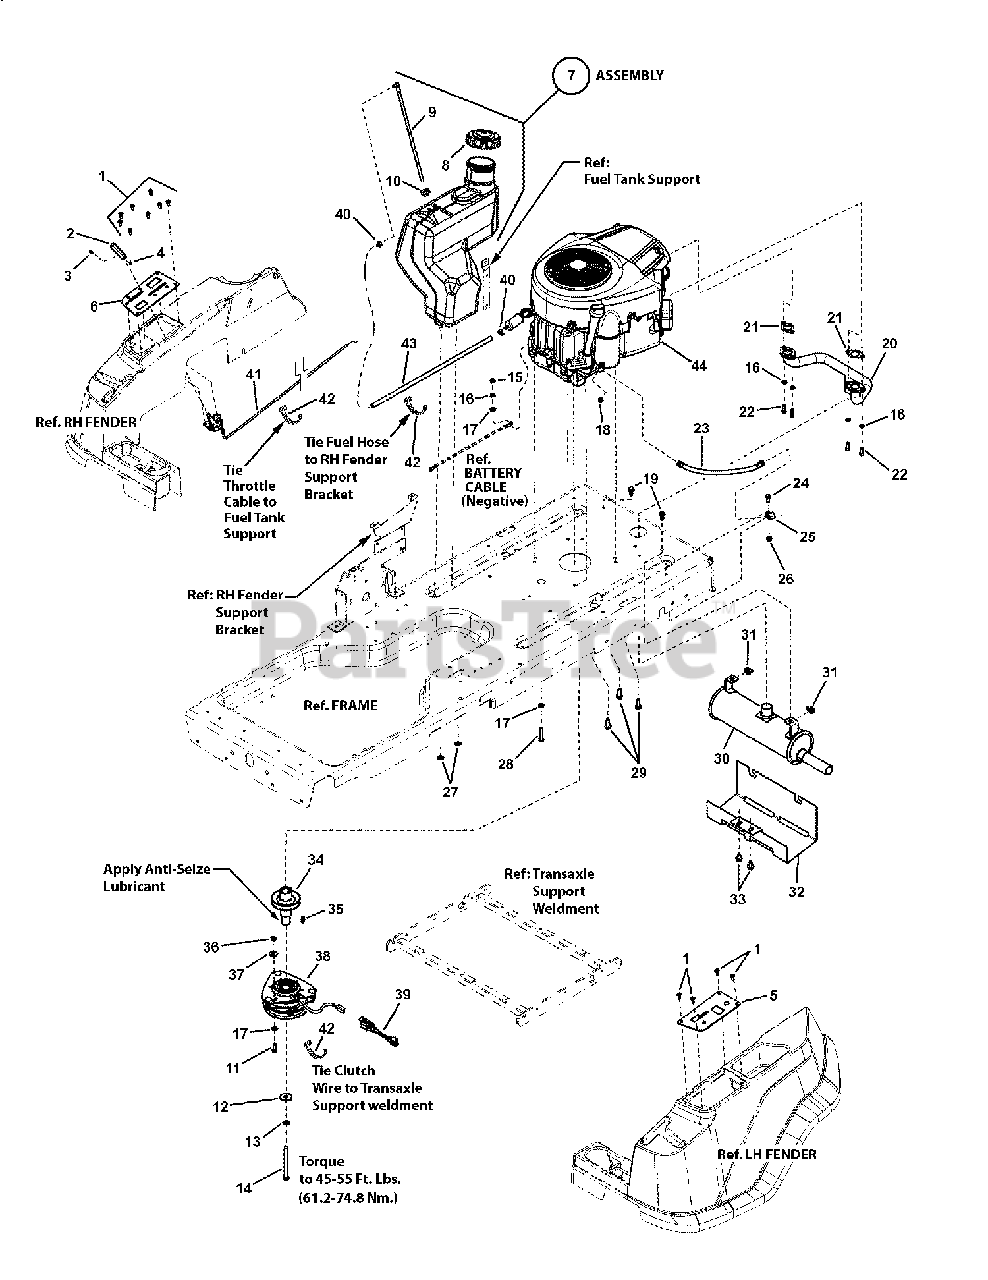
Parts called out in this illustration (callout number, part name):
1	SCREW, 1/4-20 x 5/8" Pan Head Self-Tap (Torx)
2	KNOB, Throttle, Red
3	SCREW, #8-32 x 3/8" Cross Recess Filister Head, GR 2
4	NUT, #8-32 Hex, GR 2B
5	PANEL, Control, LH
6	PANEL, Control, RH
7	ASSEMBLY, Fuel Tank, 3 Gallon (incl. 4 items shown below)
8	CAP, Fuel Tank
9	ASSEMBLY, Elbow, Pickup Tube
10	BUSHING, Fuel
11	SCREW, 5/16-18 x 7/8" Hex Head Cap, GR 5, YZ
12	WASHER, .468 ID x 1-1/2" OD x .188 Flat, YZ
13	WASHER, 7/16" Split Lock, YZ
14	SCREW, 7/16-20 x 4-1/2" Hex Head Cap, GR 5
15	NUT, 5/16-18 Hex, GR 5 or B, YZ
16	WASHER, 5/16" Split Lock
17	WASHER, 5/16" Flat
18	NUT, 1/4-20 Hex Flange Lock, GR 5, YZ
19	SCREW, 5/16-18 x 3/4" Hex Flange Lock, Black
20	MANIFOLD, B&S V-Twin
21	GASKET, Exhaust B&S Reg (No Chre) 273485
22	SCREW, 5/16-18 x 3/4" Allen Socket Head, GR 8 Black
23	HOSE, Oil Drain
24	SCREW, 5/16-18 x 3/4" Hex Head Cap, GR 5, YZ
25	HARNESS CLIP, 5/8"
26	NUT, 5/16-18 Flange Lock, YZ
27	RETAINER, 3/8" Bolt
28	SCREW, 5/16-18 x 1-3/4" Hex Head Cap, GR 5 YZ
29	SCREW, 3/8-16 x 1" Hex Washer Self-Tap
30	MUFFLER, RZT
31	NUT, Speed, Lug Type, 5/16-18
32	HEAT SHIELD, Muffler
33	SCREW, 3/8-16 x 5/8" Hex Washer Self-Tap
34	ASSEMBLY, Engine Pulley
35	KEY, 1/4" Square x 3/4"
36	NUT, 5/16-18 Hex Center Lock, YZ
37	FENDER WASHER, 5/16"
38	CLUTCH, Ogura JD-11
39	HARNESS, Jumper (used with Ogura Clutch only)
40	CLAMP, Fuel Hose
41	ASSEMBLY, Throttle, Choke-A-Matic, B&S V-Twin
42	CABLE TIE, 7"
43	HOSE, Fuel, 1/4" x 32"
44	* ENGINE, 26 HP, B&S Pro Series V-Twin
